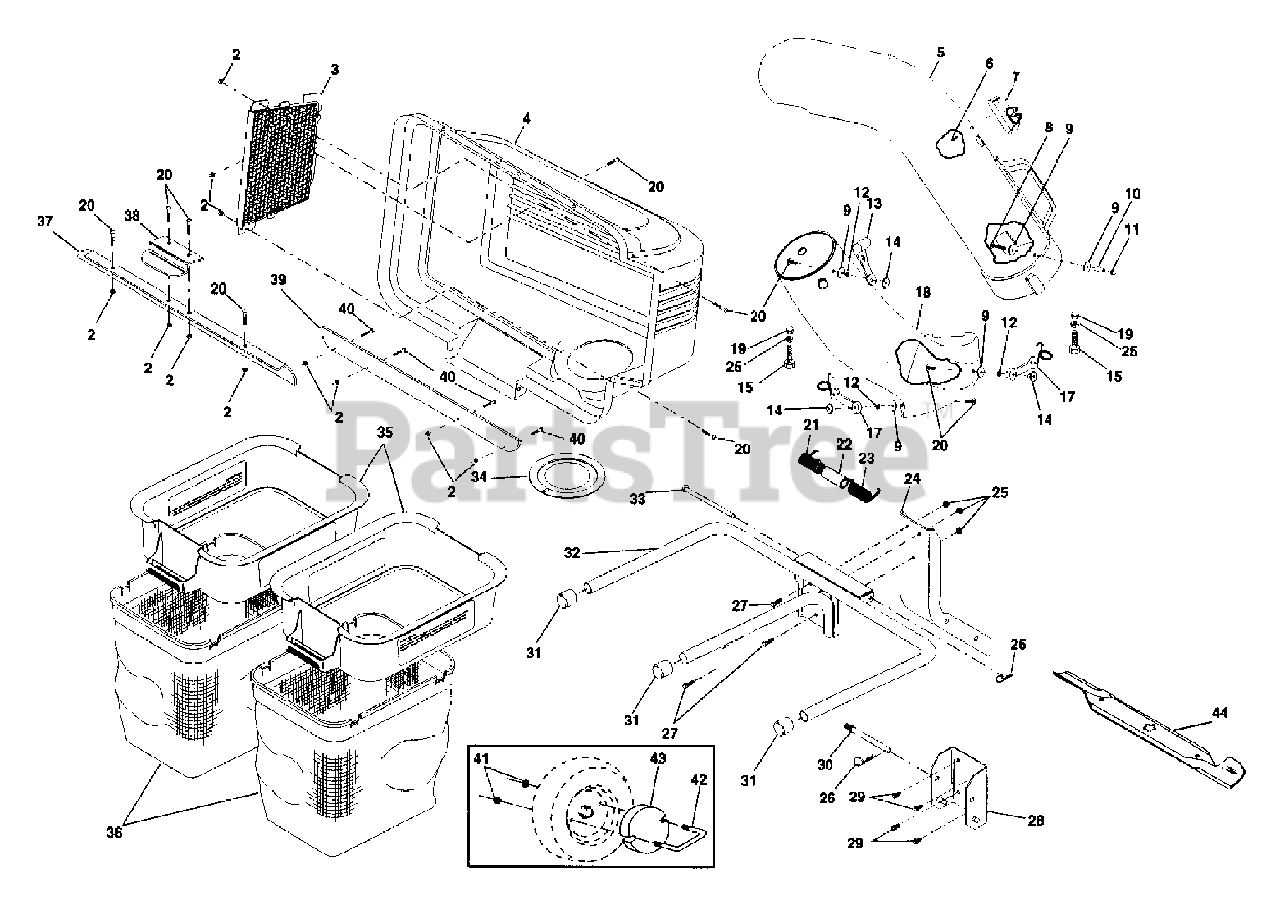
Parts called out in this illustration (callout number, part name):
3	COVER SCREEN
4	COVER BAGGER TOP
5	UPPER CHUTE
7	INDICATOR DUMP BAG
8	SCREW
10	SPACER LT
11	NUT
12	LOCKWASHER
13	HOOD LATCH T
14	WELDNUT
15	BOLT GT
17	LATCH ASSEMBLY
18	CHUTE LOWER 36"
19	ACORN NUT
21	SPRING COVER LH
22	SPACER.COVER.BAGGER
23	SPRING COVER RH
24	SUPPORT POST
26	RETAINER-SPRNG RB
27	BOLT
30	SUPPORT POST PIN
31	TUBING PLUG
32	BAGGER FRAME
33	HINGE PIN
34	GASKET COVER
35	CONTAINER TOP
36	CONTAINER BOTTOM
37	SEAL, COVER
38	LATCH CER38
39	SEAL STRIP
40	SCREW
41	NUT
43	WEIGHT, FRT WHEEL
